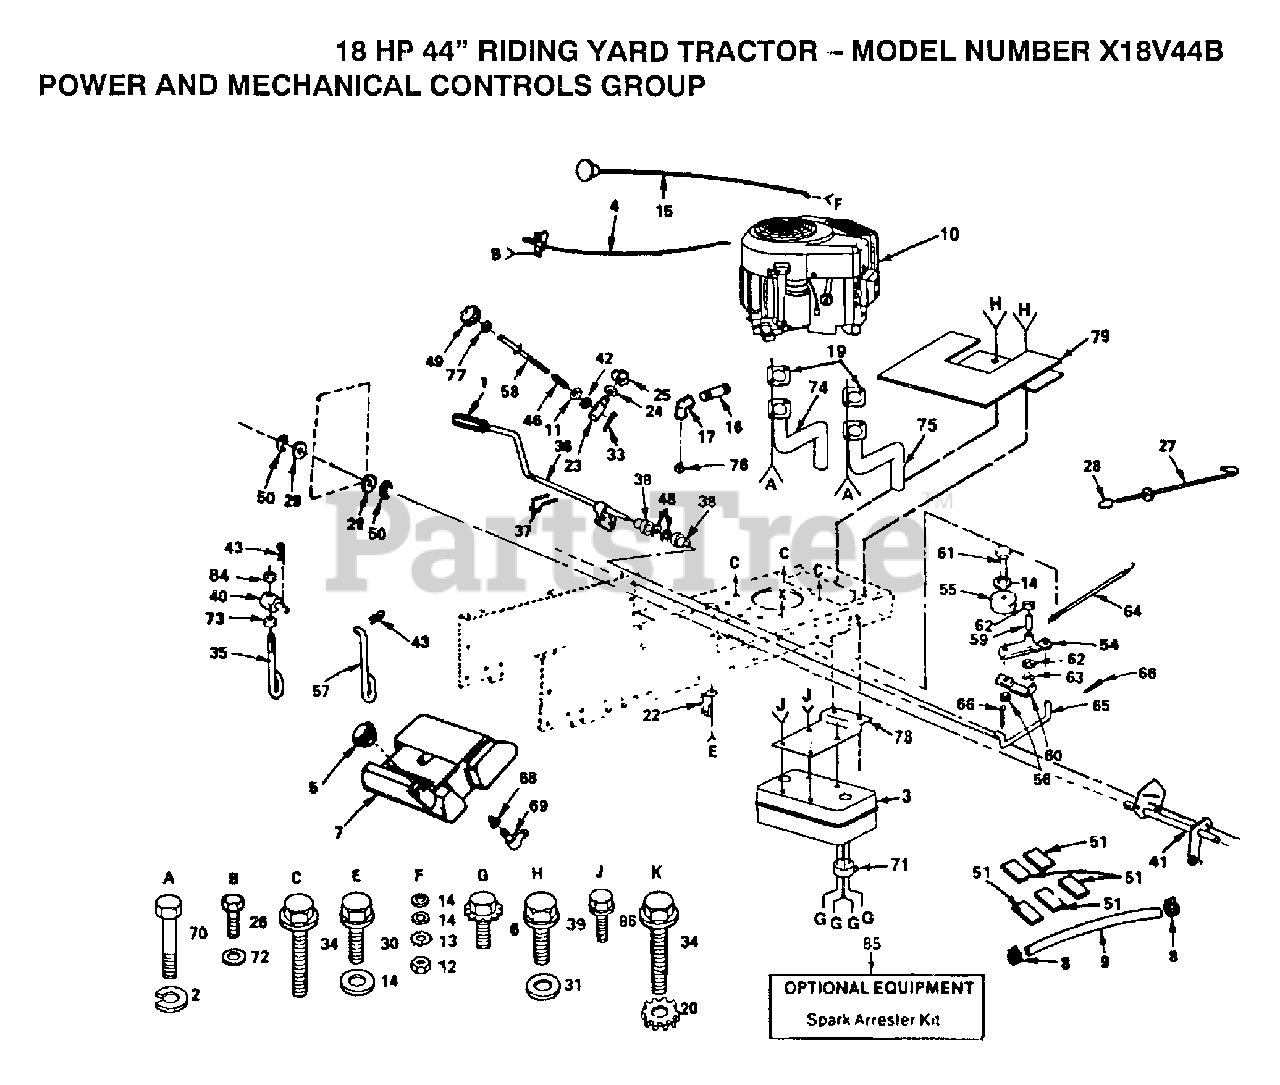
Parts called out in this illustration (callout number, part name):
1	PEDAL COVER T
2	LOCKWASHER
6	SCREW LT
8	HOSE CLAMP
9	FUEL LINE T
11	WASHER
13	LOCKWASHER
14	WASHER
16	PIPE NIPPLE LT
17	ELBOW
20	LOCKWASHER
21	LEVER ROD LT
22	RETAINER BELT
23	TRUNION LT
24	WASHER
25	KLIP RING
26	SCREW
27	ROD BRAKE PARK
28	PLUNGER CAP T
29	WASHER
30	SCREW
31	WASHER
34	SCREW LT
35	PIVOT PIN T
38	NYLON BEARING
39	SCREW
41	SHAFT LIFT LT
42	NUT T
44	GRIP
46	SPRING T
48	WASHER LT
49	HDLE ADJ LIFT
50	E-RING
51	PAD-SPACER LT
54	ARM IDLER
57	LIFT LINK LT
58	ROD LIFT LT
59	"LY, BEARING"
60	RETAIN BELT
62	WASHER LT
63	KLIP RING
64	"SPRING, RETURN LT"
65	"LINK, CLUTCH T"
66	COTTER PIN
68	BUSHING OUTLET T
69	FUEL TANK STEM GT
71	DEFLECTOR.222573
73	NUT
77	NUT
78	BRACKET MUFFLER
81	"BOLT,HEX"
86	SCREW ST
